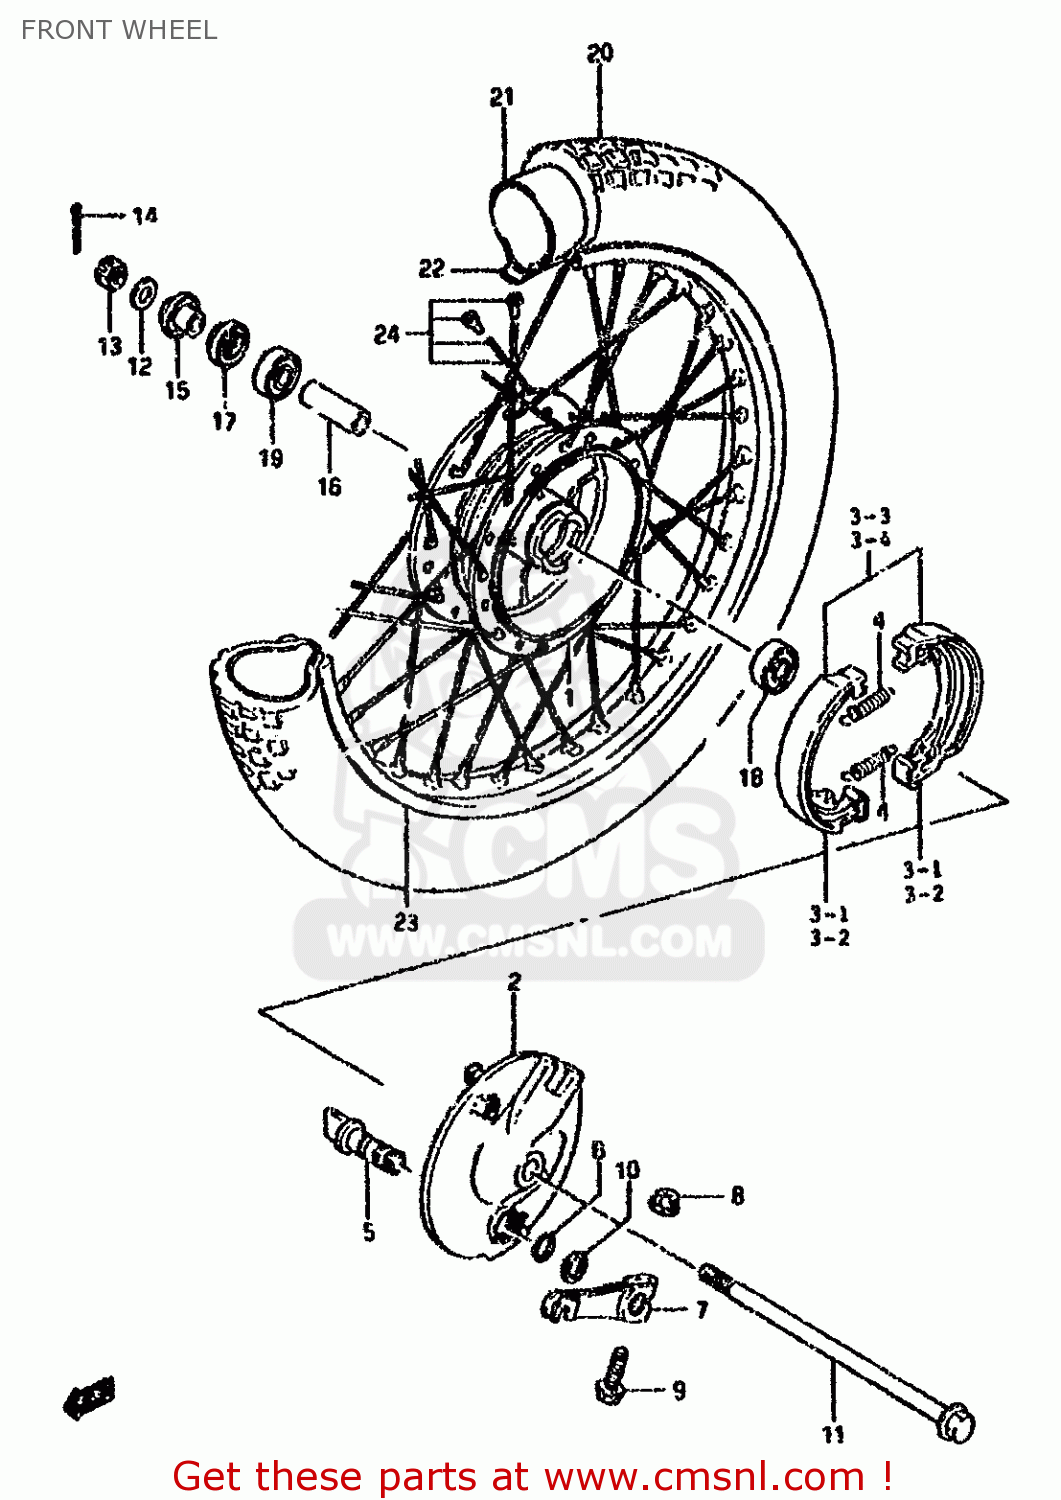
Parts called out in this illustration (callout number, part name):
1	HUB,FR
2	PANEL,FR BRAKE ANCHOR
3	SHOE,BRAKE
4	SPRING(L:35.8)
5	CAM,FR BRAKE
6	O-RING (D:2.4 ID:13.8)
7	LEVER,FR BRAKE CAM
8	NUT
9	BOLT
10	WASHER (14.5X22X1.6)
11	AXLE,FR
12	WASHER
13	NUT
14	PIN 20X20
15	SPACER,FR AXLE,R
16	SPACER (10.2X16X51)
17	SEAL,OIL(15X31X5)
18	BEARING
19	BEARING
20	TIRE(2.25 14)
21	TUBE,INNER
22	PROTECTOR,INNER TUBE
23	RIM,FR WHEEL(1.40X14)
24	SPOKE SET,FRONT
